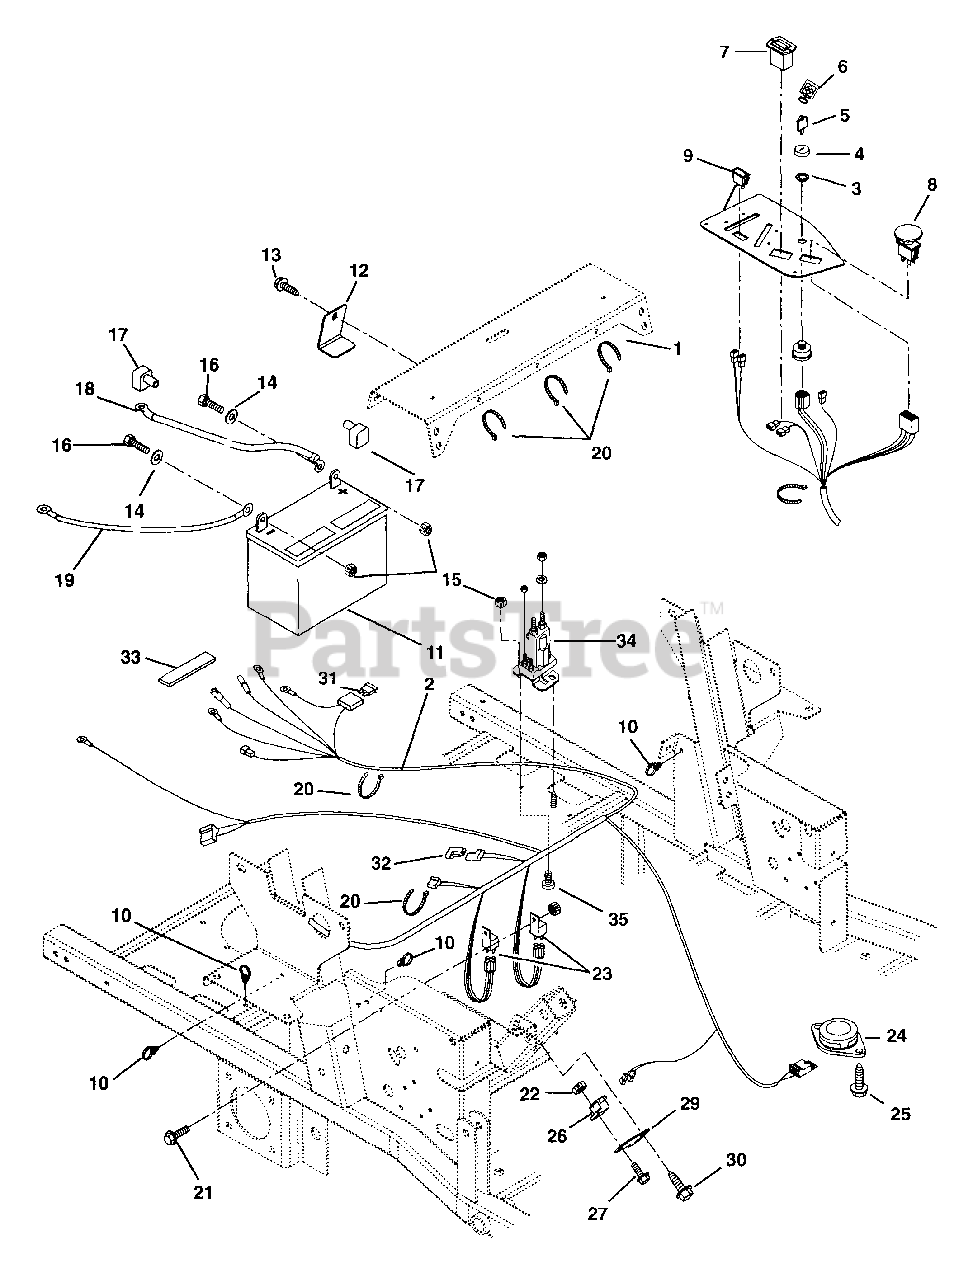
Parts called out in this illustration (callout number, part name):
1	Key Switch
2	Harness Kohler
2	Wire Harness-Briggs
3	Nut-Panel .562-24
4	Cap-Ignition Switch
5	Ignition Switch Key
6	Key Chain
7	Hour Meter
8	Switch-Clutch With Retainer Ring
9	Light-Indicator
10	Tube Clip .75
11	Battery with Tube
12	Clamp-Battery
13	Screw-Tapping .25-20 x .50 Hex Washer Head
14	Washer-Flat-Steel .281 x .620 x .065
15	Nut-Locking-Center .25-20
16	Bolt-Hex .25-20 x .75 Grade 5
17	Insulator
18	Start Cable 22"
19	Ground Cable
20	Cable Tie
21	Screw-Machine 10-24 x .50 Hex Washer Head
22	Nut-Locking-Nylon 10-24 With Insert
23	Relay
24	Seat Switch
25	Screw-Tapping 12-24 x .50 Hex Washer Head
26	Switch-Single Pole
27	Screw-Machine 10-24 x .75 Hex Washer Head
29	Plate-Switch
30	Screw-Tapping .38-16 x .50 Hex Washer Head
32	Molded Diode Plug-Black 1-Amp
33	Pad-Battery
34	Solenoid-Starting
35	Bolt-Hex .25-20 x .50 Grade 5
